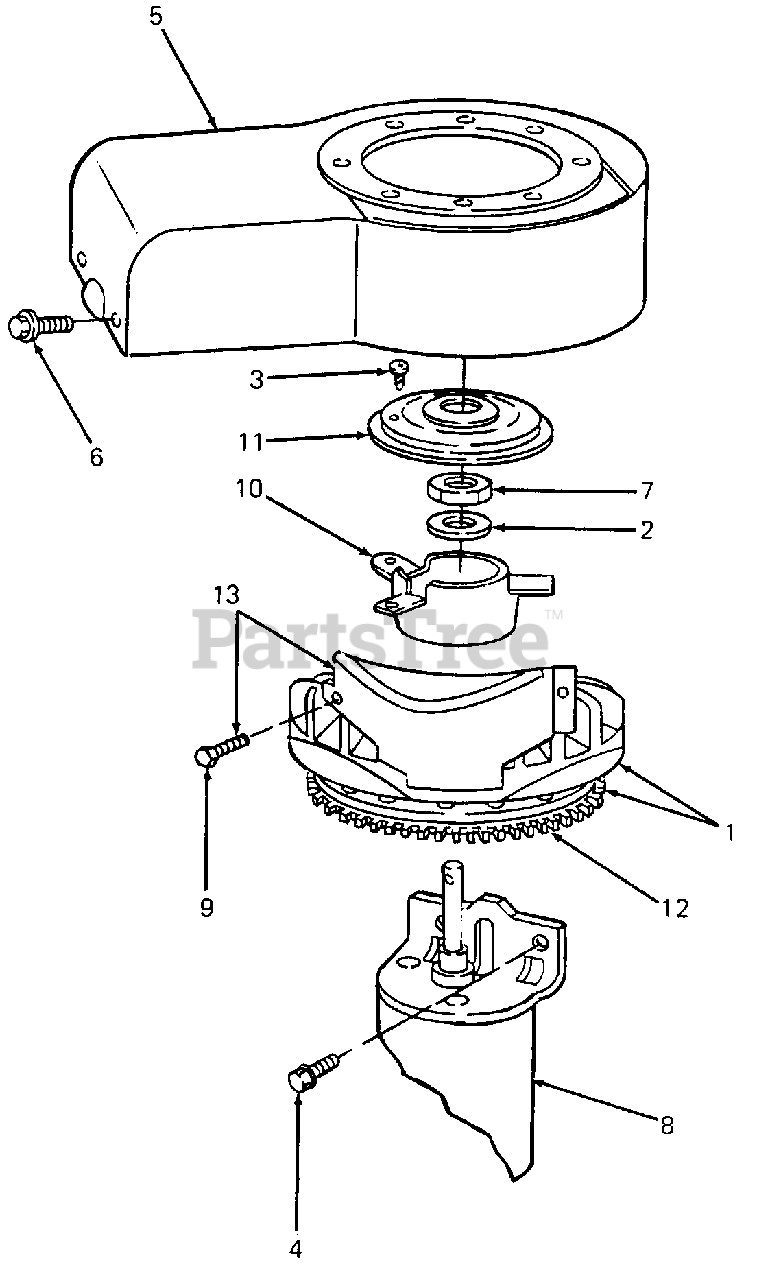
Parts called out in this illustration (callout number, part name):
1	Flywheel & Ring Gear Assy - Magneto
2	Washer, Spring
3	Screw, Sems
4	Screw, Sems
5	Housing, Blower
6	Screw, Blower Housing Mtg Sems
7	Nut, Hex
8	Motor, Starting
9	Screw, Sems
10	Cup, Screen Mounting
11	Screen, Flush Rotating
12	Gear, Ring
13	Cover, Starter
